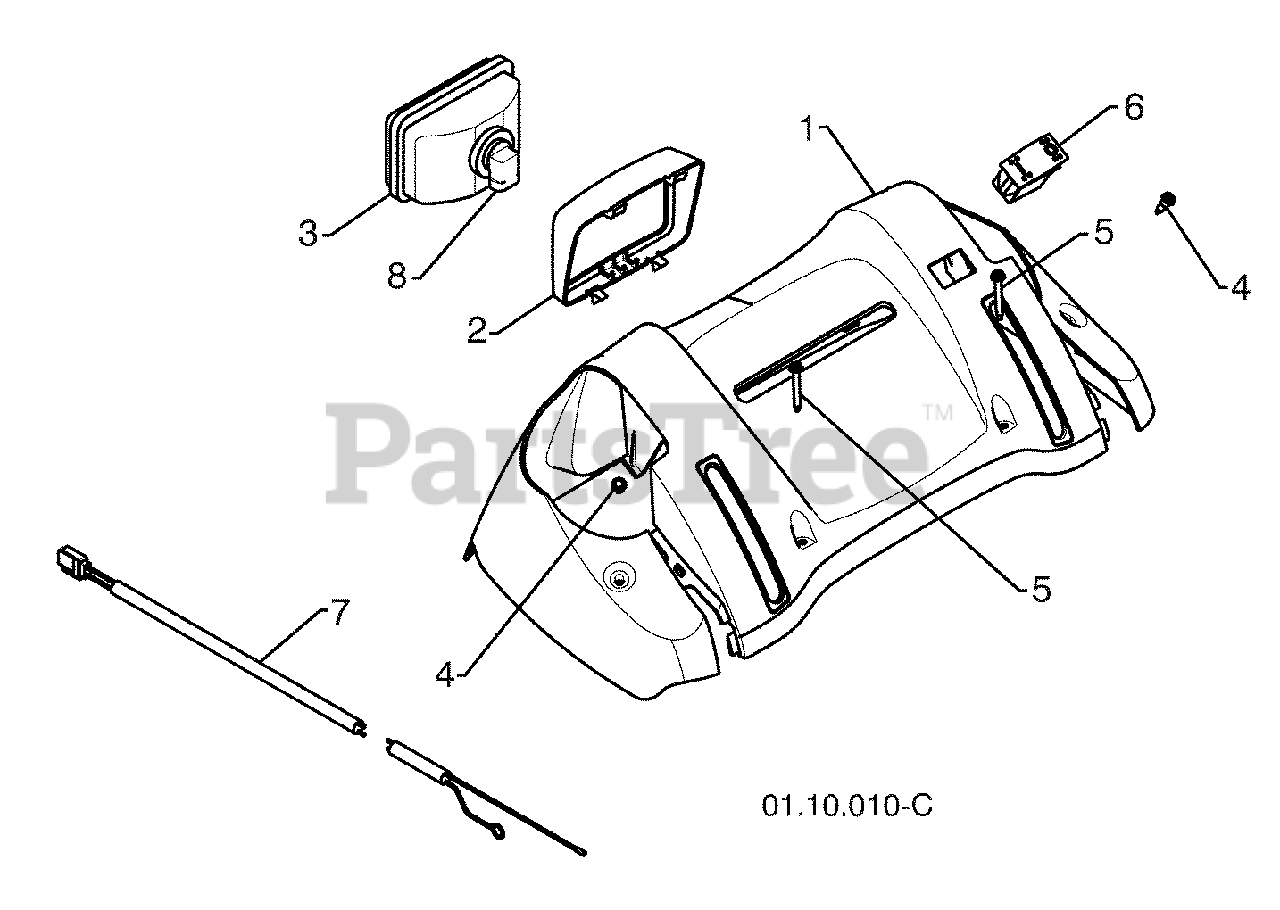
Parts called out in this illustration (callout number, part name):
1	CONSOLE PANEL GRAY
2	HEADLIGHT BEZEL GRAY
3	HALOGEN HEADLIGHT
4	SHOULDER SCREW 10-24 X .625
5	SCREW 10-24 X 1.25
6	GRIP SWITCH
7	WIRE HARNESS
